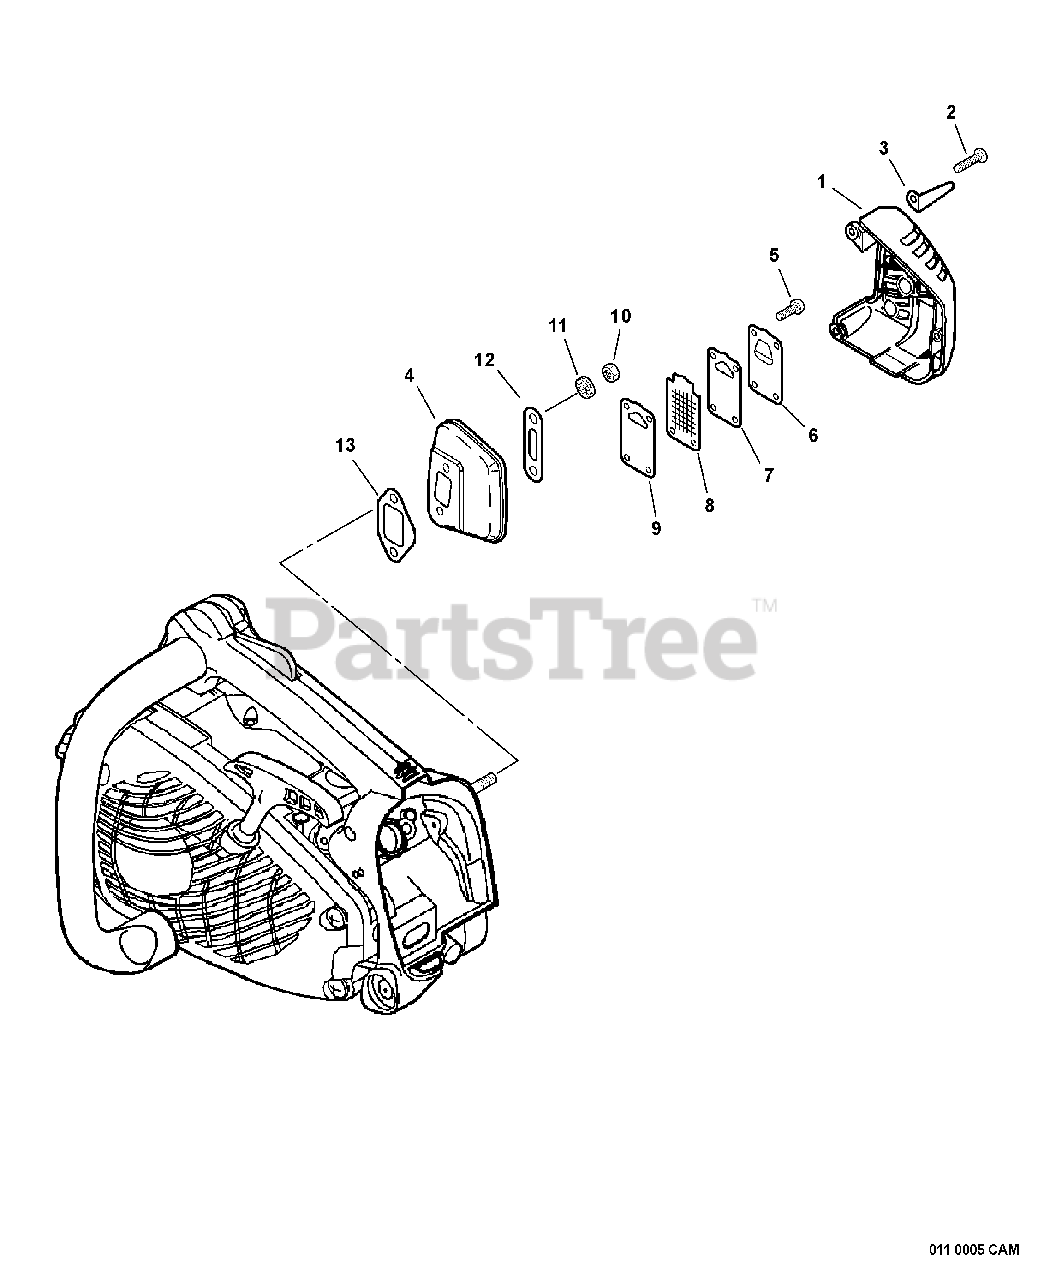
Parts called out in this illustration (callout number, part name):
1	COVER, EXHAUST
2	SCREW - 4X16
4	MUFFLER
5	SCREW - 4X12
6	GUIDE, EXHAUST
7	GASKET, EXHAUST
8	SCREEN, SPARK ARRESTOR
9	GUIDE, EXHAUST
11	LOCKWASHER
13	GASKET, EXHAUST
